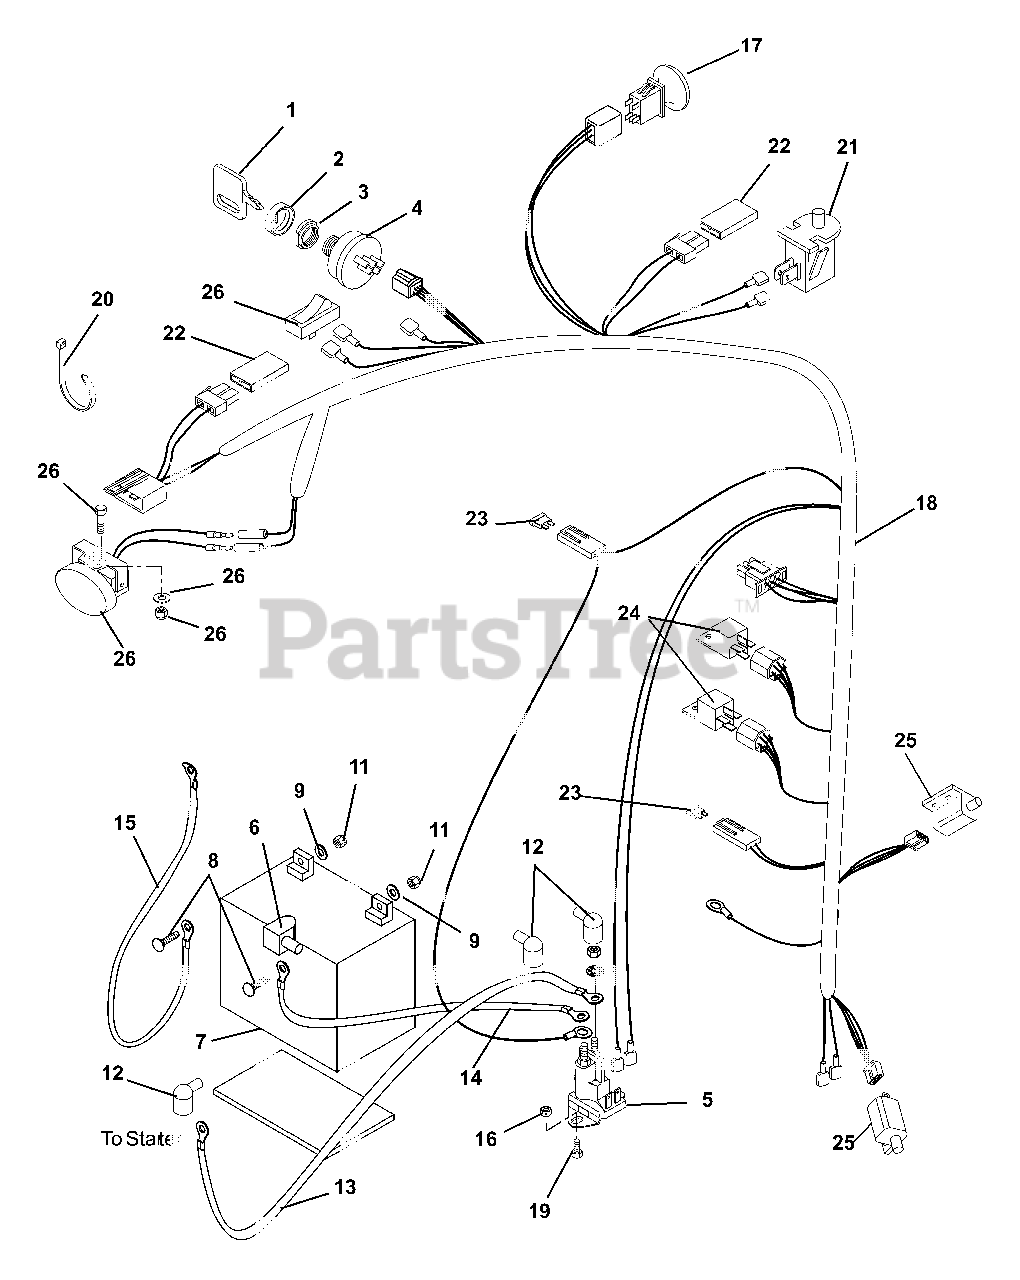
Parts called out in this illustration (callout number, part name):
1	Key with Cap
2	Cap, Ignition Switch
3	Nut, Panel .625-32
4	Key Switch
5	Solenoid
6	Insulator
8	Bolt, Hex .25-20 x .75 Grade 5
9	Washer, Flat Steel .281 x .62 x .065
10	Washer, Locking .25 x .062 Regular
11	Nut, Hex .25-20
12	Boot, Eyelet Terminal
13	Cable, Positive Battery
14	Starter Cable 13"
15	Starter Cable 16"
16	Nut, Spin Lock Flange .312-18
17	Switch, PTO NMIR
18	Harness, Reverse No Mow Wire
19	Screw, Tapping 10-24 x .375 Hex Washer Head
20	Cable Tie
21	Switch- Snap Mounting (N.O.)
22	Diode, Connector Shell
23	Fuse, 25 AMP
24	Relay
25	Switch, Interlock
26	Light Kit
